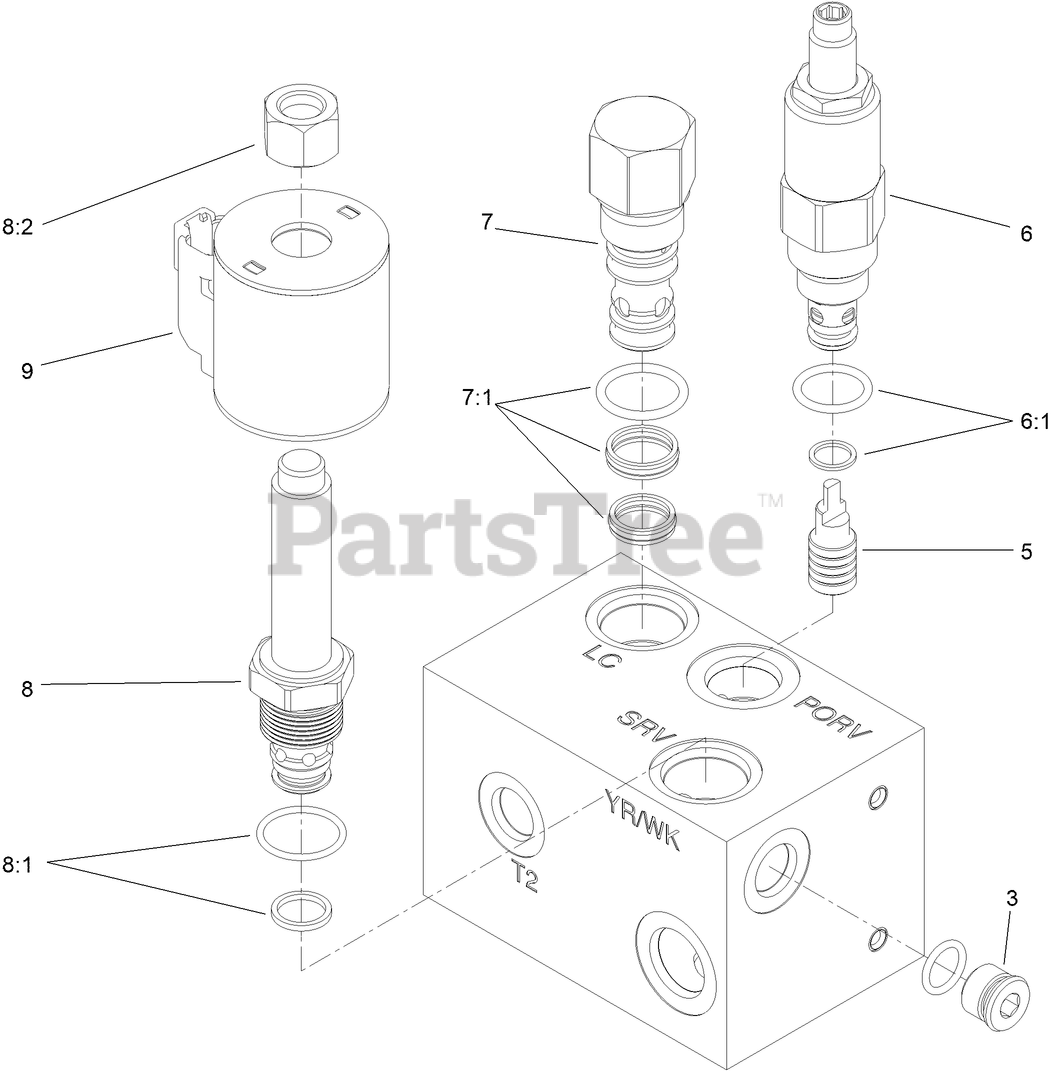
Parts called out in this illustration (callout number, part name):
3	PLUG-HYD
5	PISTON-PILOT
6	VALVE-RELIEF
6:1	SEAL KIT
7	ELEMENT-LOGIC, VENTED
8	VALVE-RELIEF,
8:1	SEAL KIT
8:2	NUT-COIL (9/16-24 UNEF-2B)
9	COIL-SOLENOID
